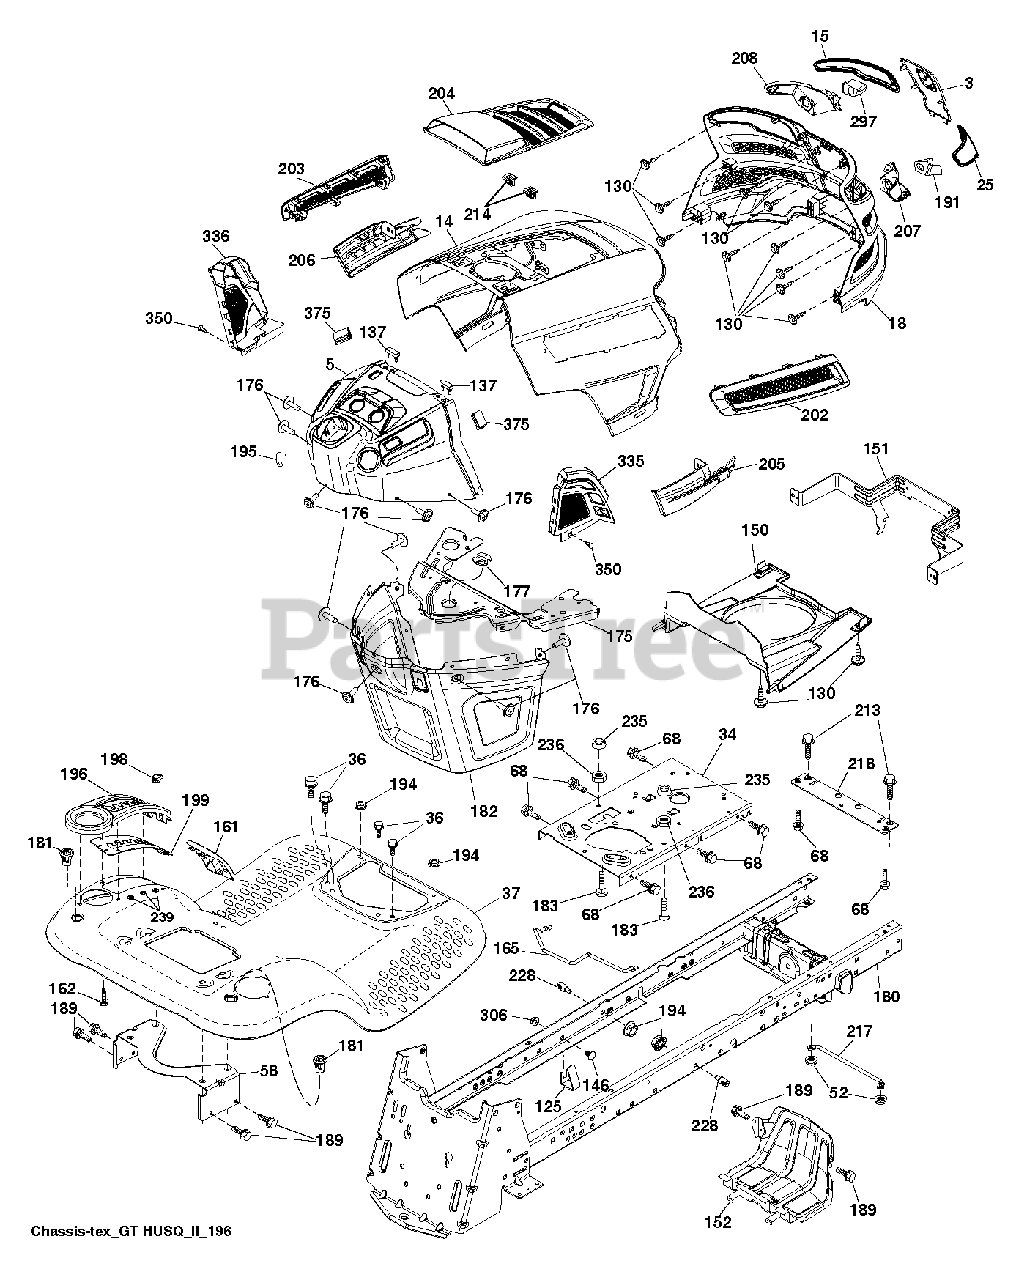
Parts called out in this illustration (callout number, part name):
3	APPLIQUE.SUBASM.GT.HUSQ.II
5	DASH.UPP.GT2.DUAL.RD.PT
14	HOOD.ASM.HUSQVARNA.GT.TEX.ORAN
15	LENS.HEADLIGHT.LH.GTII.2011
18	GRILLE SUBASM.GT.II.LOW.HDLGHT
25	LENS.HEADLIGHT.RH.GTII.2011
34	PLATE.ENGINE.WELDED.CHASSIS
36	SCREW 5/16"
37	FENDER.PNT.TXGT.ERGO.SD FILL
52	LOCKNUT
58	BRKT.SUPPORT.FNDR/TANK
68	SCREW LT
125	CLIP.FUEL.LINE
130	SCREW.#10 X 0.750.BOS
137	BUMPER DASH
146	BOLT.RDHD.SHT.SQNK.3/8-16X5/8
150	AIR.DUCT.GTV.BLACK
151	BRACKET.PIVOT.HOOD.GT.HUSQ.II
152	SHIELD.BROWNING.W/TEX
161	CONSOLE.FUEL WINDOW.STGT.498
162	SCREW.HI-LO.CONSOLE
165	SUPPORT.TANK.REAR.W/TEX
175	PLATE.CROSSMEMBER.HUSQ
176	SCREW.#10-24X5/8.RN.QU
177	BUSHING STEERING
180	CHASSIS.GT.SLOPED.DRAWBAR.
181	BUSHING.MNT.FEND.CRGO.TEX.49
182	DASH.LOWER.COMMON.12V.ADAPTOR
183	BOLT.5/16-18X1-1/4 FULL THD
189	SCREW
191	INSERT.REFLECTIVE.RH.HUSQ.GTII
194	NUT LOCK HEX FLANGE 5/16-18
195	PLUG.HOLE.DASH.LOWER.12V.BLK
196	CONSOL.DECKLIFT.7-POSITON.STGT
198	INDICATOR.DECK.LIFT.RED
199	PLATE DECK LIFT
202	VENT.SIDE.RH.GT.HUSQ.II.
203	VENT.SIDE.LH.GT.HUSQ.II.498
204	VENT.TOP.HUSQ.GT2
205	SIDE.TRIM.RH.GT.HUSQ.II
206	SIDE.TRIM.LH.GT.HUSQ.II.GRAY
207	HEADLIGHT.CUP.BEZEL.HUS.GT2.RH
208	HEADLIGHT.CUP.BEZEL.HUS.GT2.LH
213	BOLT
214	CLIP.RETAINER.TINNER.
217	ROD.PIVOT.HOOD
218	X-PIECE.HOOD.STOP.NON/
228	STUD.FASTNER.W/ANTI-ROTATE
235	SPACER FENDER
236	NUT.CENTERLOCK.5/16-
239	NUT.PUSH.156
297	INSERT.REFLECTIVE.LH.HUSQ.GTII
306	NUT LOCK FLG 3/8-16 UNC
335	COVER.LOWER.DASH.RH.BLACK
336	COVER-LH.LOWER.DASH.GT2.BLACK
350	CLIP.X-MAS.TREE
375	BUMPER CLIP-ON. DASH 1"
